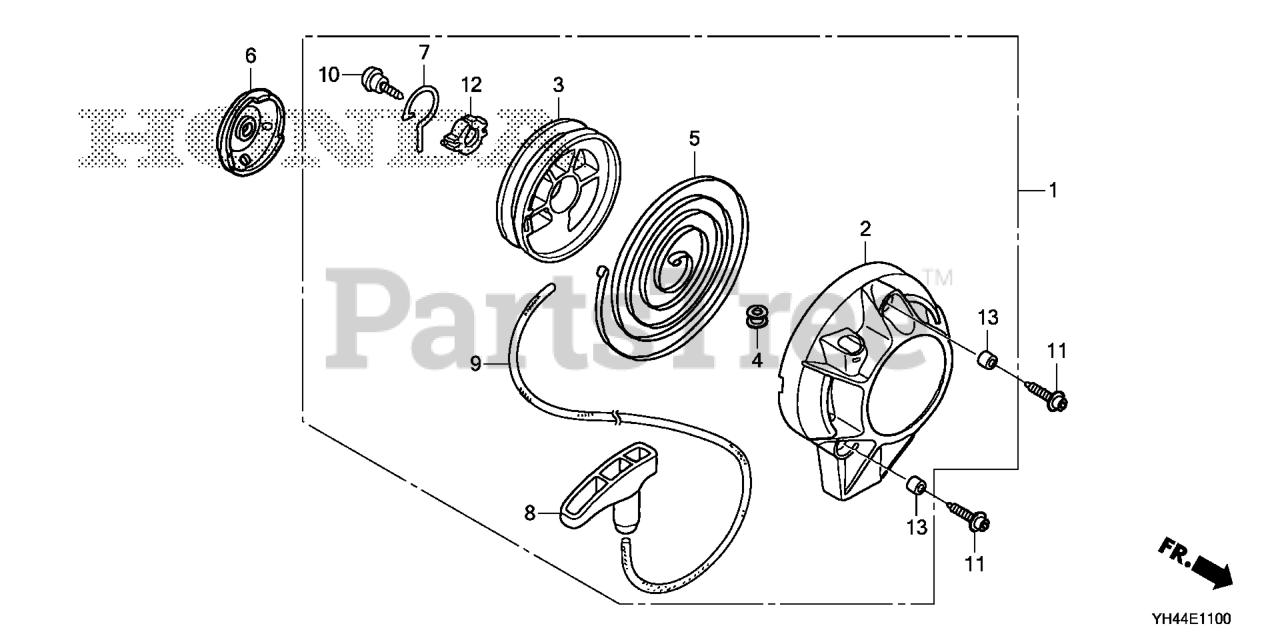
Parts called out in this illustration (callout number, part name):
1	STARTER ASSY., RECOIL
2	CASE, RECOIL STARTER
3	REEL, RECOIL STARTER
4	GUIDE, ROPE
5	SPRING, RECOIL STARTER
6	PULLEY, RECOIL STARTER
8	KNOB, RECOIL STARTER
9	ROPE, RECOIL STARTER (#3.5X40")
10	SCREW, SETTING
11	BOLT, SOCKET (5X16)
13	COLLAR A, HEAD COVER
